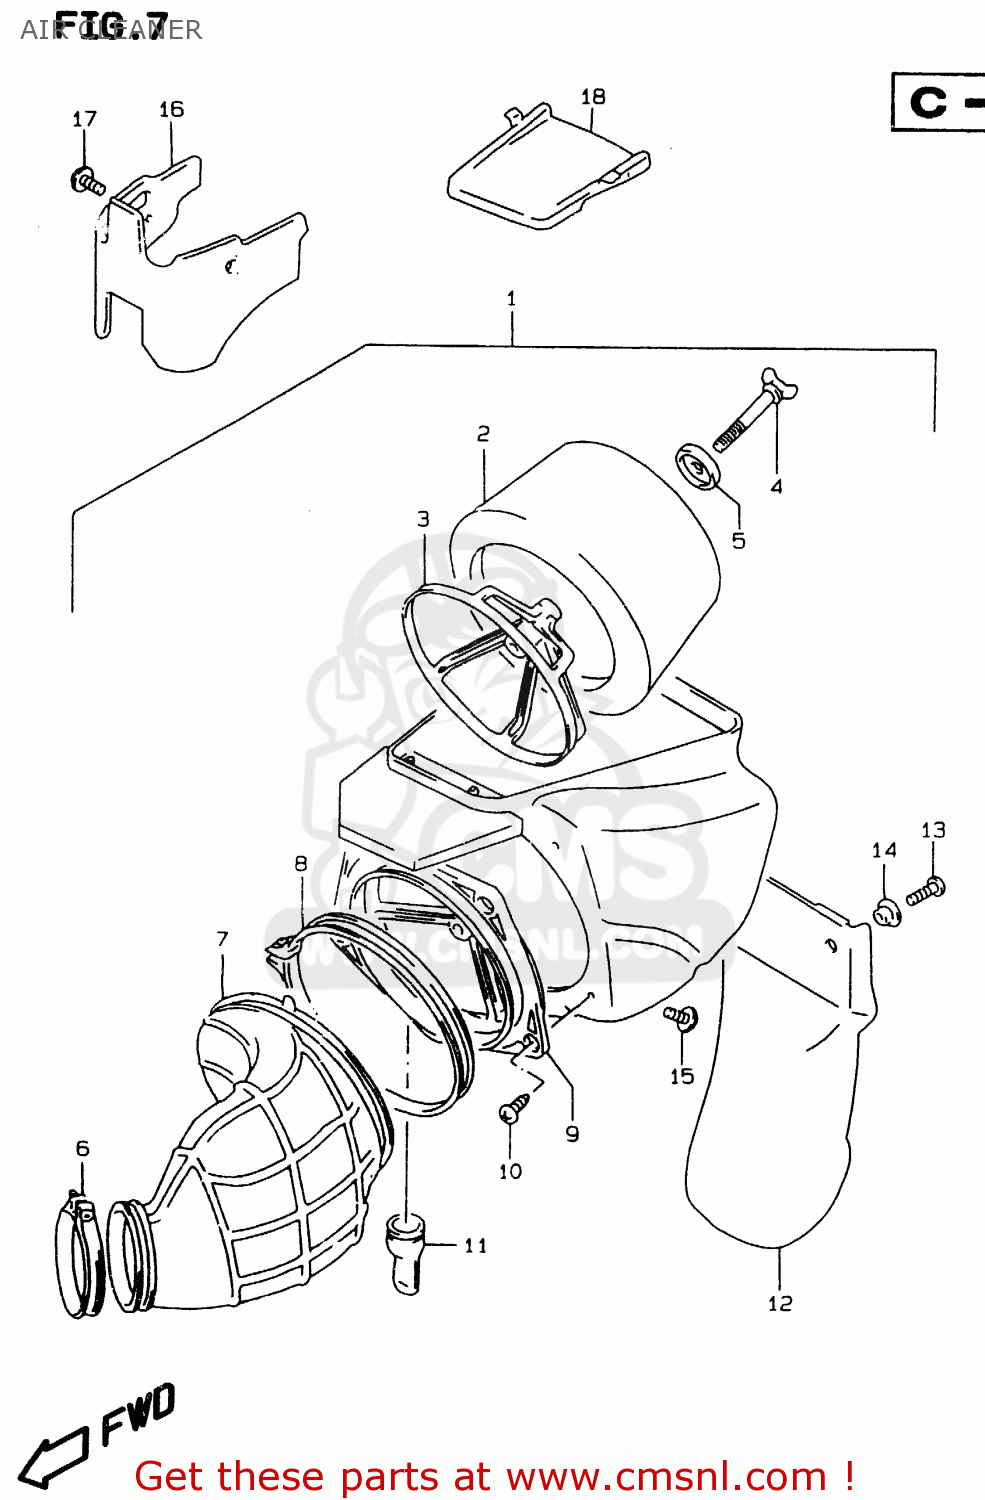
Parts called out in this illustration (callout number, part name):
1	CLEANER ASSY,AIR
2	FILTER
3	HOLDER,FILTER
4	BOLT,WING
5	WASHER,AIR CLEANER
6	CLAMP
7	TUBE,OUTLET
8	CLAMP
9	BASE,FILTER
10	SCREW
11	CAP,DRAIN
12	GUARD,MUD LWR
13	SCREW
14	COLLAR
15	BOLT
16	GUARD,MUD
17	SCREW(6X12)
18	CAP,AIR CLEANER
